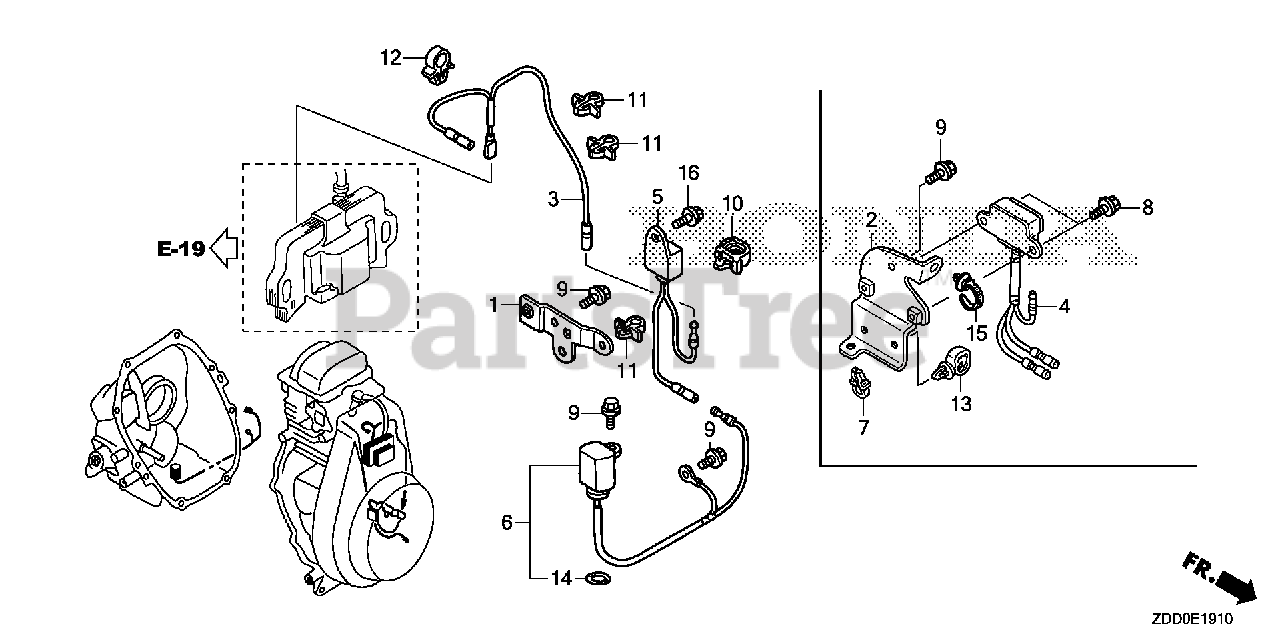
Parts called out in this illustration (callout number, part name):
1	BRACKET, OIL ALERT UNIT
3	WIRE, STOP SWITCH
5	ALERT UNIT, OIL
6	SWITCH ASSY., OIL LEVEL
9	BOLT, FLANGE (6X14)
10	CLIP, WIRE HARNESS (10MM)
11	CLIP, CABLE (A)
12	CLIP B, CABLE
14	O-RING (11.8X2.4)
16	BOLT, FLANGE (6X8)
